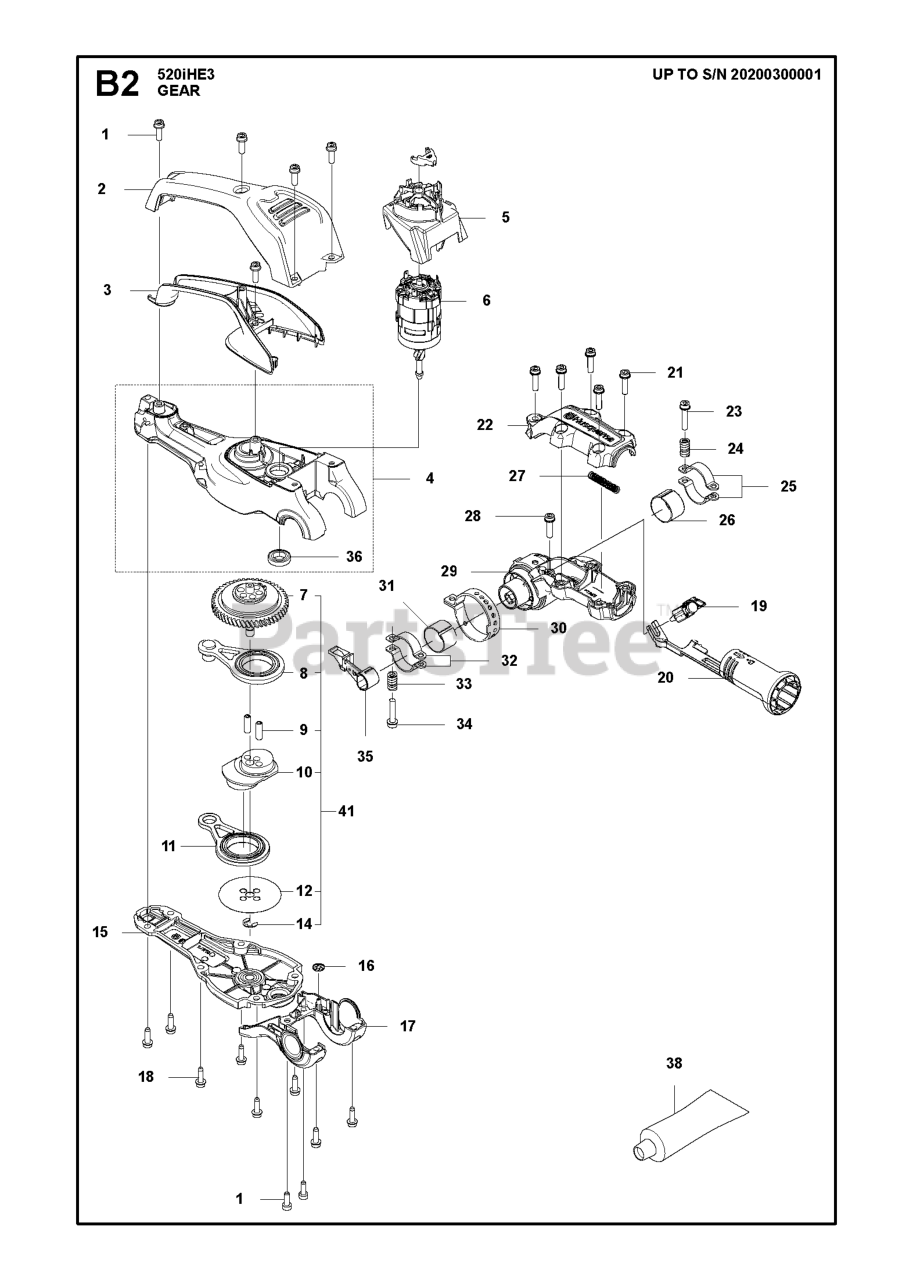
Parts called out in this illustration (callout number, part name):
1	SCREW IHSCFT
3	MOTOR COVER LOWER
5	AIR CONDUCTOR MOTOR
7	GEAR ASSY
8	CONNECTING ROD ASSY
9	HEAVY DUTY DOWEL PIN PROJEKT 1
10	ECCENTRIC DISC GEAR
11	CONNECTING ROD ASSY
12	WASHER DISK DISC
14	LOCK WASHER
16	LOCK WASHER
17	BEARING CAP
18	SCREW IHSCFT
19	LOCKING PIN ASSY
20	HANDLE GRIP
21	SCREW IHSCFT
25	BRAKE BAND ASSY POLE HEDGETRIM
26	SLIDE RING
27	COMPRESSION SPRING
28	SCREW IHSCFT
29	HOUSING JOINT
30	RING INDEX 520IHE3/IHT4
31	SLIDE RING
32	BRAKE BAND ASSY POLE HEDGETRIM
36	BALL BEARING
38	GREASE 20G HEDGE TRIMMER GEAR
41	GEAR ASSY GEAR ASSY KIT 520IHE
